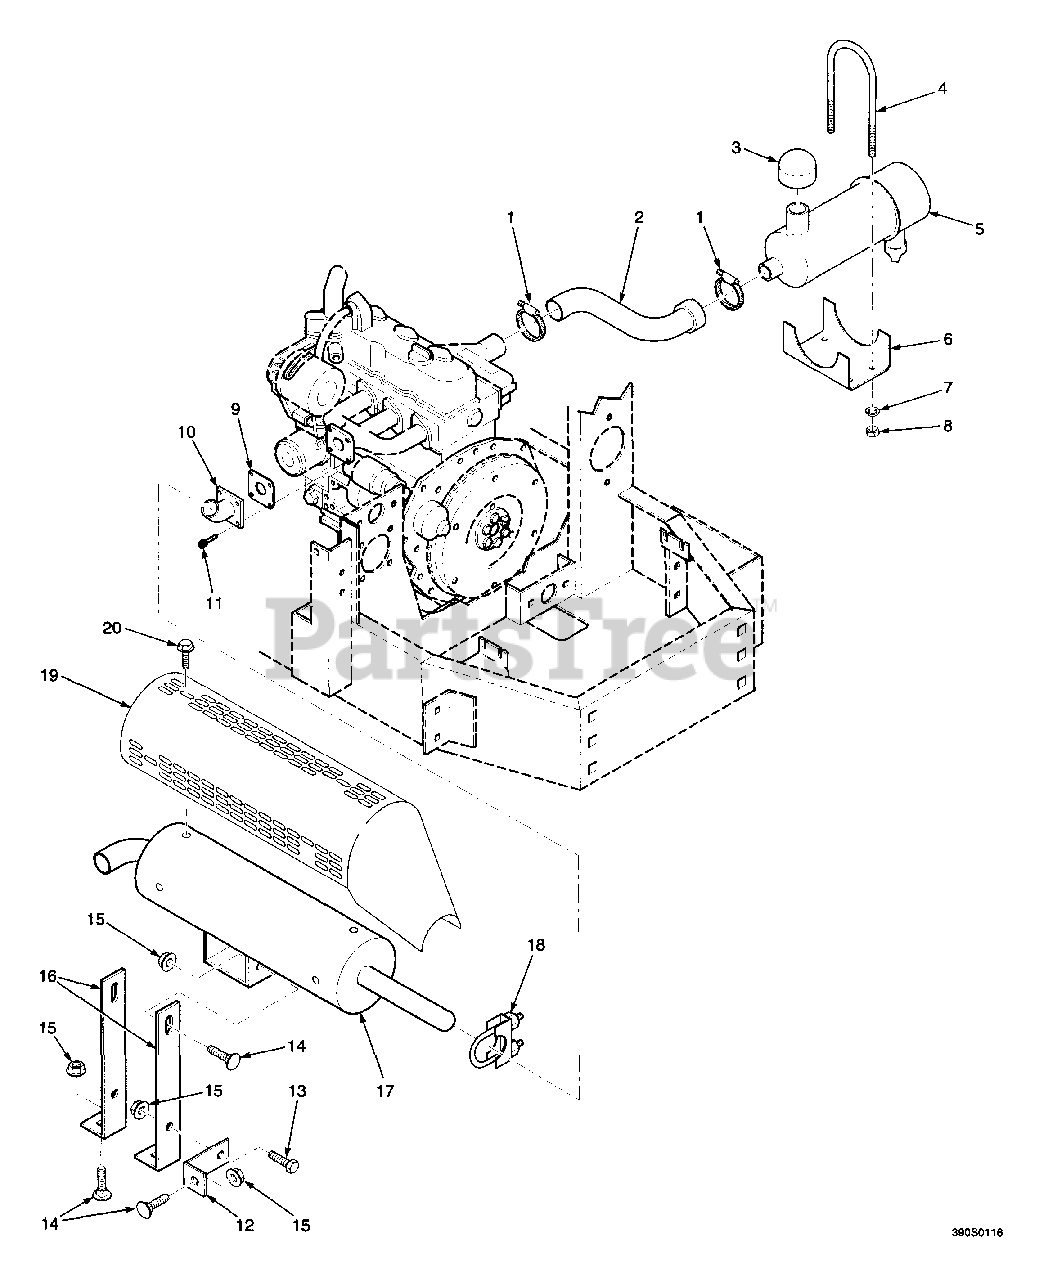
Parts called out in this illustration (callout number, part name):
1	Hose Clamp
2	Hose, Air Intake
3	Cap. Precleaner
4	U-Bolt
5	Air Cleaner
6	Mounting Bracket, Air Cleaner
7	Lockwasher, 5/16
8	Nut, Hex, 5/16-18
9	Gasket, Manifold
10	Adapter, Manifold
11	Capscrew, Socket Head, M8-1.125 x 20
12	Brace, Muffler Support
13	Bolt, Hex Head, 5/16-18 x 1
14	Carriage Bolt, 5/16-18 x 3/4
15	Serr. Fl. Hex Nut, 5/16-18
16	Bracket, Muffler Support
17	Muffler
18	Clamp, Exhaust Pipe
19	Muffler Guard
20	Screw, 10-32 x .50 Type F HH
